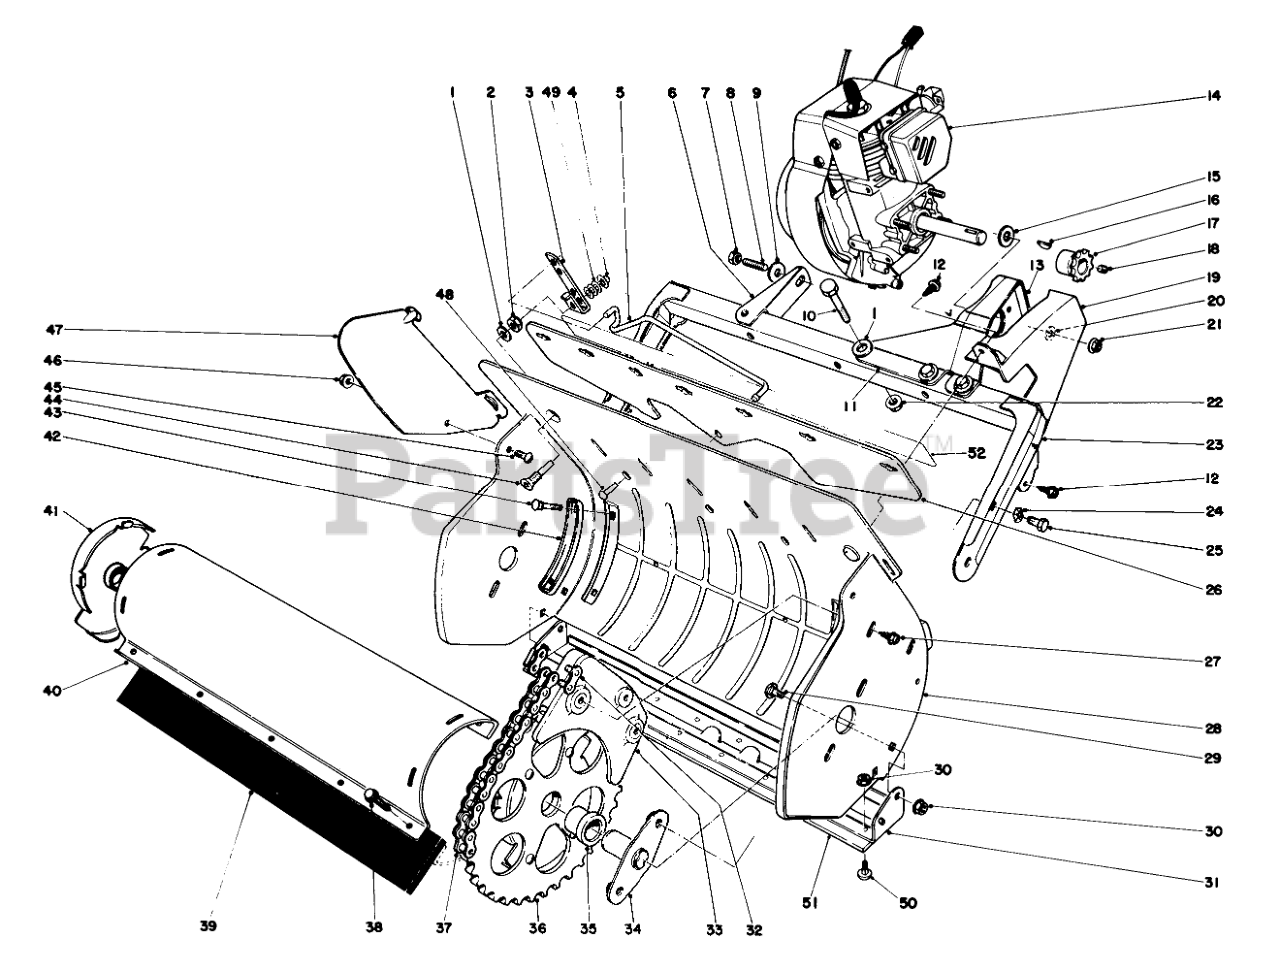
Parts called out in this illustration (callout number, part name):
1	WASHER-FLAT
2	NUT-LOCK, NI
3	Bracket Vane Adjustment
4	NUT-SPEED
5	Linkage Vane Adj.
6	Frame Bracket
7	NUT-LOCK, CONE
9	WASHER
10	SCREW-HH
11	Engine Bracket Internal
12	SCREW-HWHTF
13	Engine Bracket External
14	Engine
15	WASHER-PLAIN
16	KEY-WOODRUFF
17	SPROCKET
18	SCREW-HSH
19	Chain Guard
20	Lockwasher
21	NUT-HF
22	NUT-LOCK, HHF
23	Frame
24	Washer
25	Screw
26	Vane Mount
27	SCREW-HWHTF
28	Housing
29	SCREW-CARR
30	NUT-KEPS
31	Scraper Support
32	LINK-CONNECTING, NO. 35
33	Stripper
34	ROTOR SHAFT ASM
35	ROTOR BUSHING
36	End Cap Assembly L.H. (Incl. Ref. #35)
37	ROLLER CHAIN
38	Screw
39	ROTOR BLADE
40	ROTOR SHELL
41	End Cap Assembly R.H. (Incl. Ref. #35)
42	Handle Plate
43	SCREW-CARR
44	Screw
45	SCREW-PTH
46	NUT-LOCK, FLANGE
47	Vane
48	Pop Pivot
49	WASHER-FLAT
50	SCREW-CARR
51	SCRAPER
52	Decal-Warning
